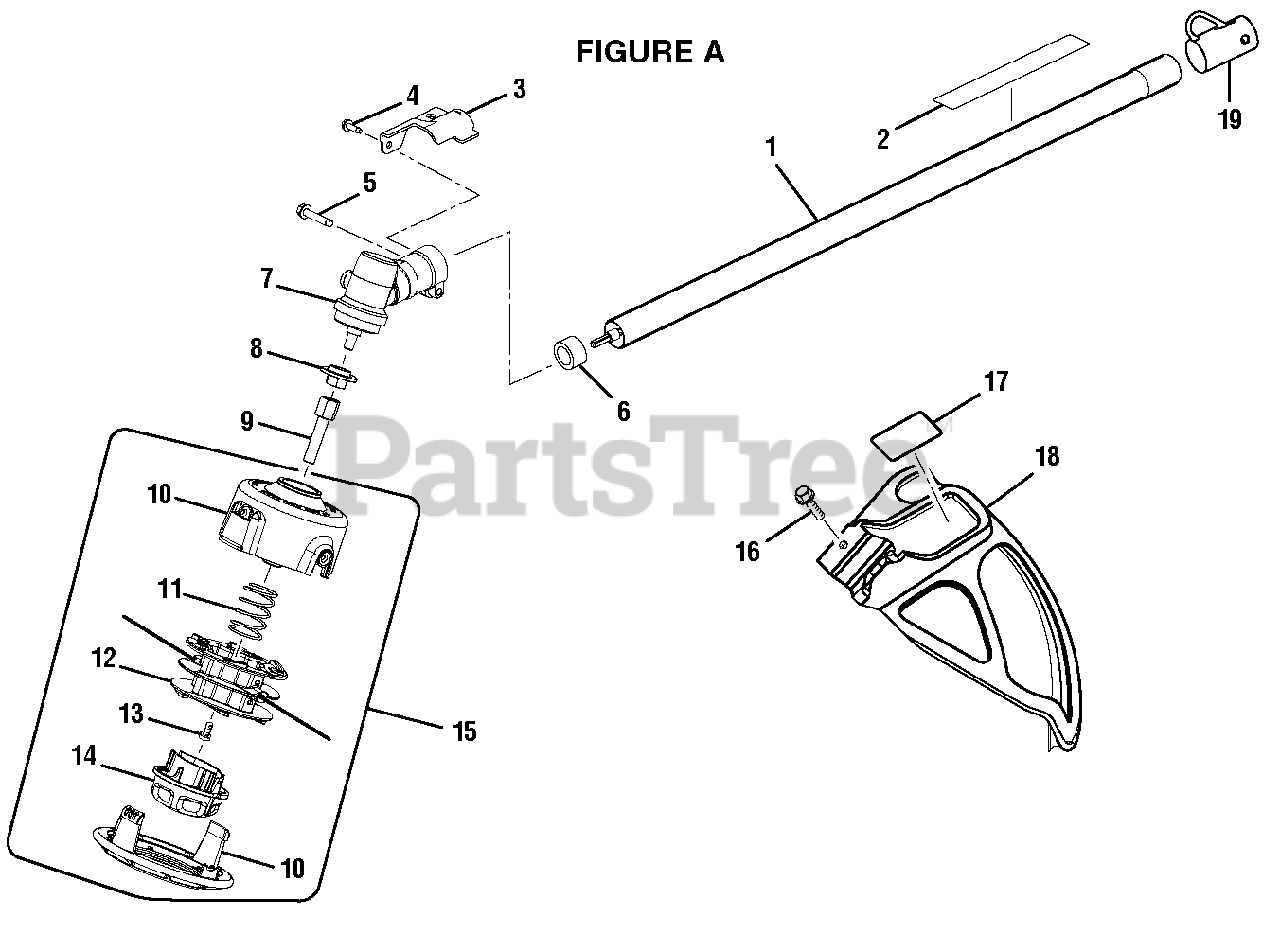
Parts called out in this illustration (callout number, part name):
1	Straight Shaft Assembly
2	Warning Label
3	Grass Deflector Clamp
4	Screw (#10-24 x 5/8 in. Hex Washer Hd.)
5	Screw (1/4-20 x 1-1/4 in.)
7	Gear Case Assembly
8	Flanged Washer
9	Trimmer Head Shaft Adaptor
10	Stringhead Housing
11	Compression Spring
12	Spool
13	Bolt (5/16-18 x 1/2 in., L.H.)
14	Bump Knob
15	Trimmer Head Assembly (.095)
16	Screw (#1/4-20 x 1-1/4 in. Hex Washer Hd.)
17	Grass Deflector Label
18	Grass Deflector Assembly
19	Hanger Cap
